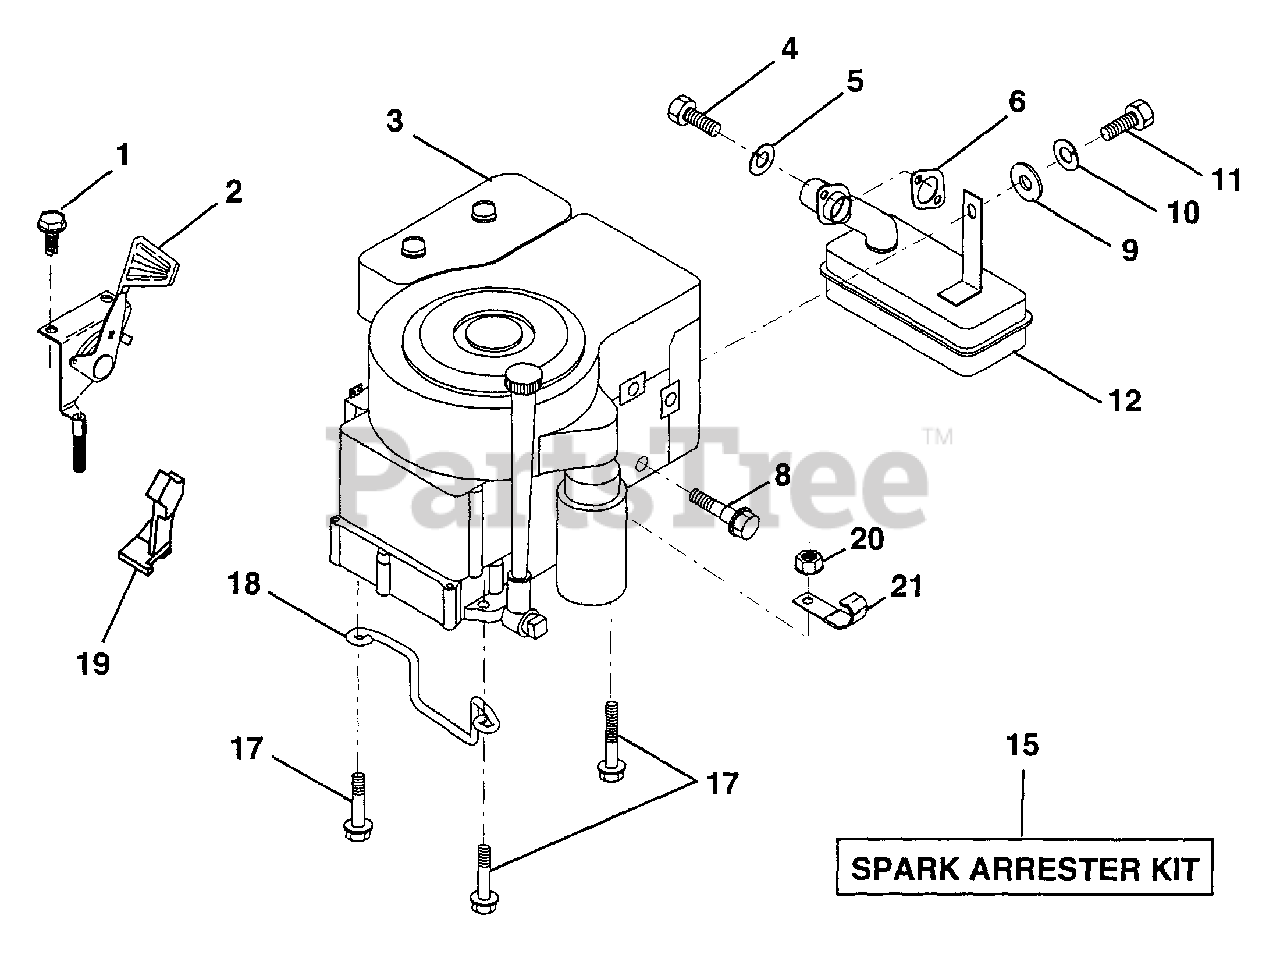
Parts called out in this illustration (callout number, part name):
1	Screw, Hex Head, Thread-Cutting 1/4-20 x 1/2
2	Control, Throttle
3	Engine
4	Screw, Hex Cap Head 5/16-18 x 3/4
5	Washer, Lock, Heavy Helical Spring 5/16
6	Gasket, Exhaust
8	Bolt, Shoulder 5/16 UNC
9	Washer 5/16 x 3/4 x 16 Gauge
10	Washer, Lock, Heavy Helical Spring 1/4
11	Bolt Hex Fin
15	Arrester, Spark
17	Screw, Hex Washer Head, Thd., Roll. 3/8-16 x 1-1/2
18	Keeper, Ground Drive Belt
19	Stop, Throttle
20	Nut Keps Hex 3/8-16 UNC
21	Clip Line Fuel
